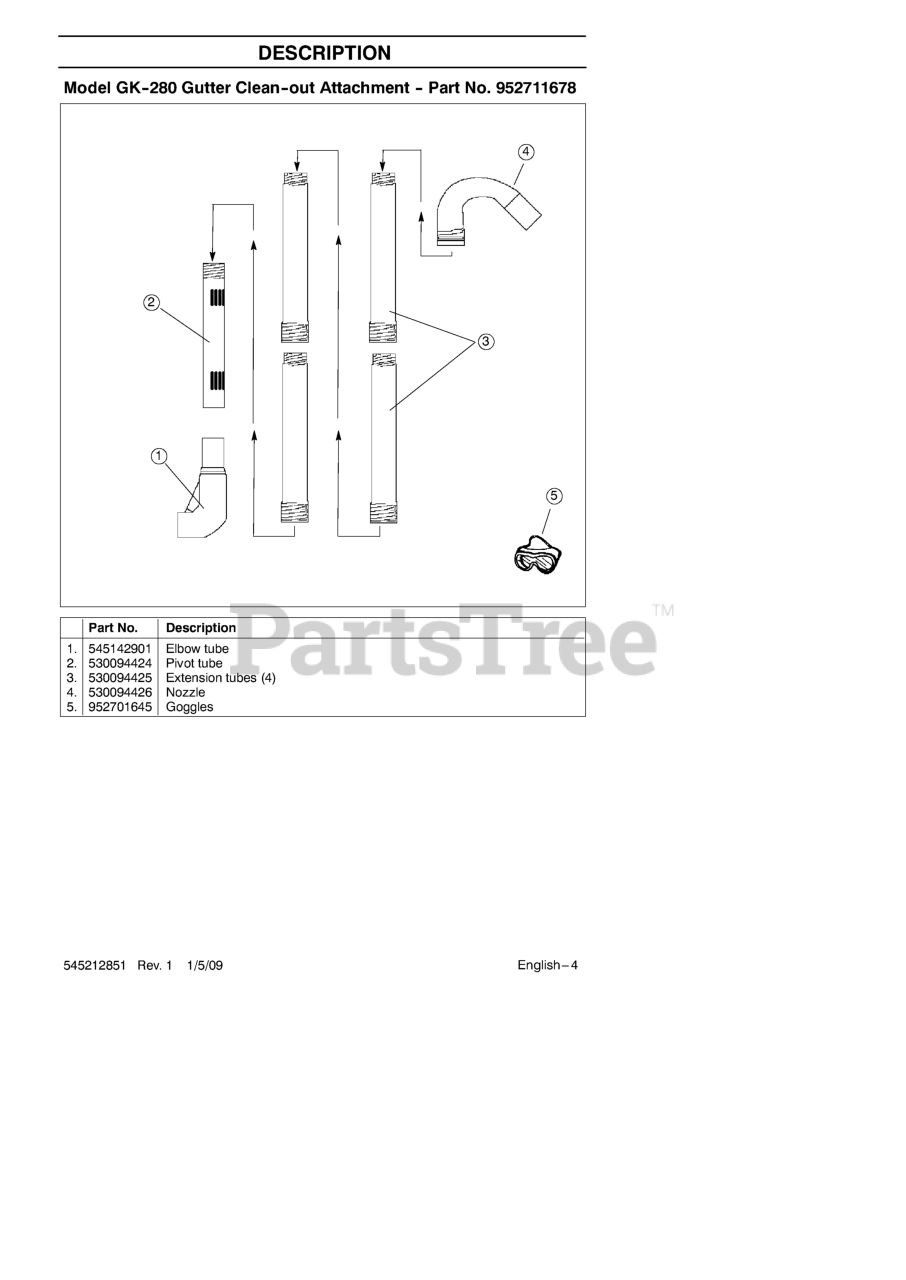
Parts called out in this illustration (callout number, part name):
1	ELBOW TUBE
2	PIVOT TUBE
3	EXTENSION TUBES
5	GOGGLES
NI	GUTTER CLEAN-OUT ATTACHMENT
